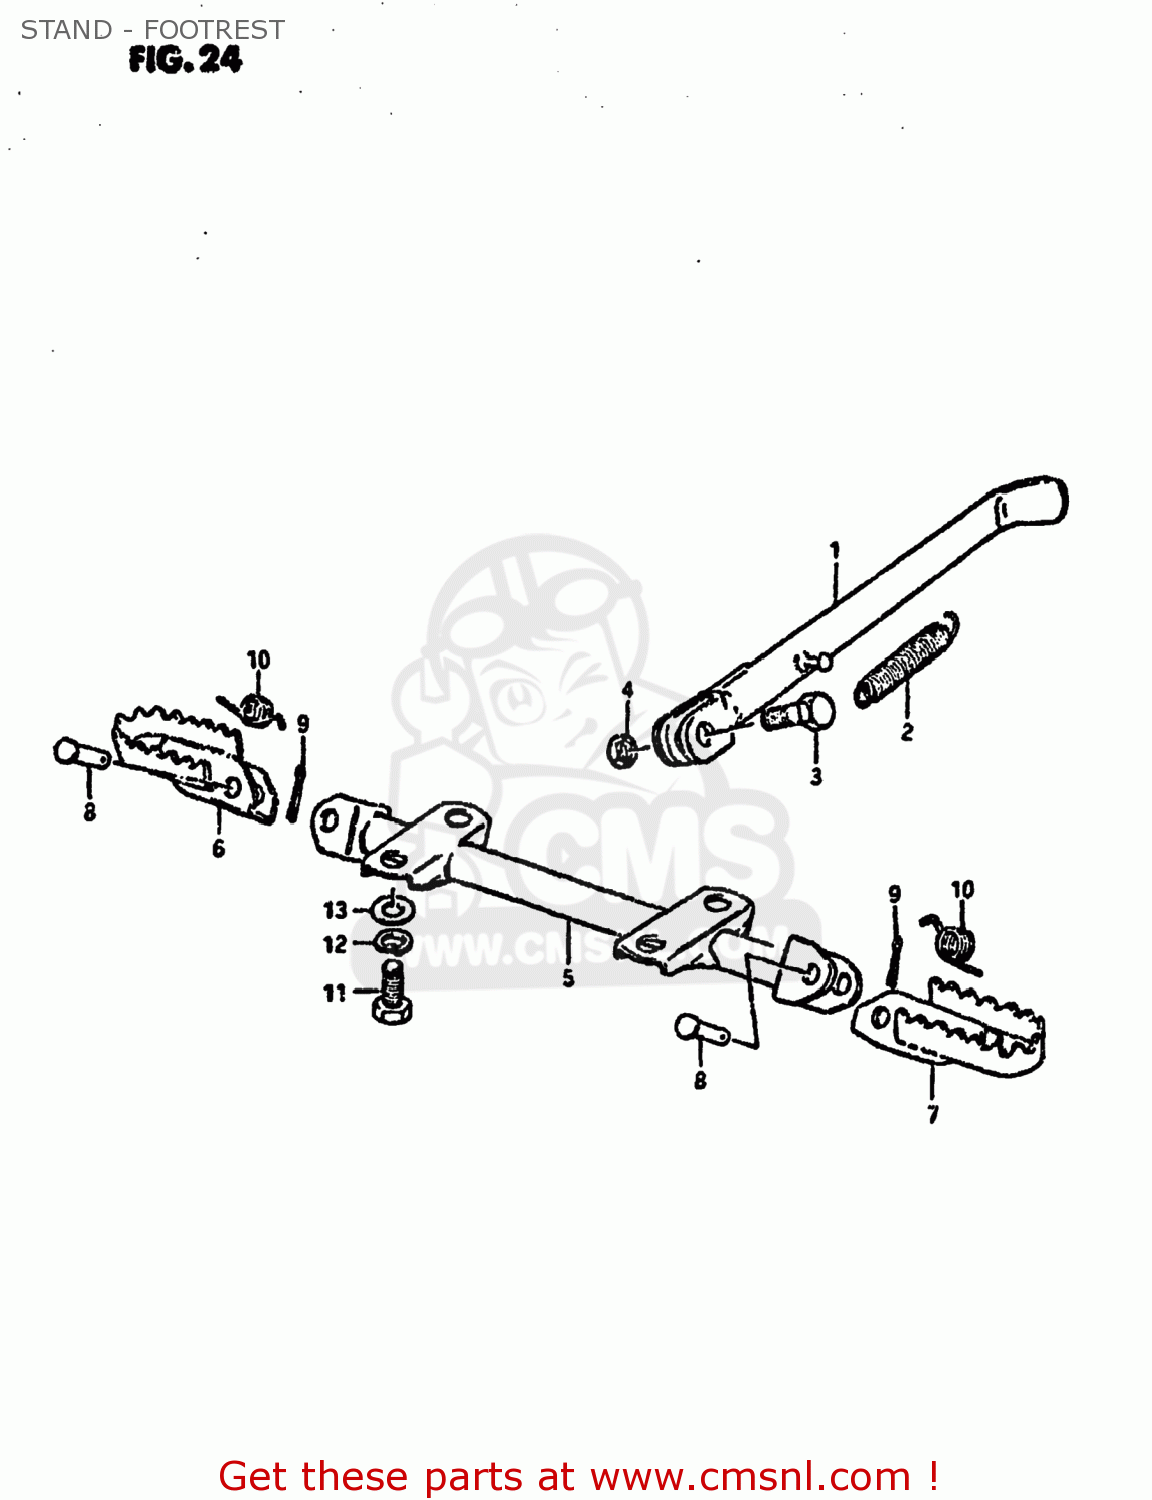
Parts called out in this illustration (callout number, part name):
1	STAND,SIDE
2	SPRING
3	BOLT(10X30)
4	NUT
5	BAR,FR FOOTREST
6	FOOTREST,FR,R
7	FOOTREST
8	PIN
9	PIN 20X20
10	SPRING
11	BOLT
12	LOCK WASHER
13	WASHER
